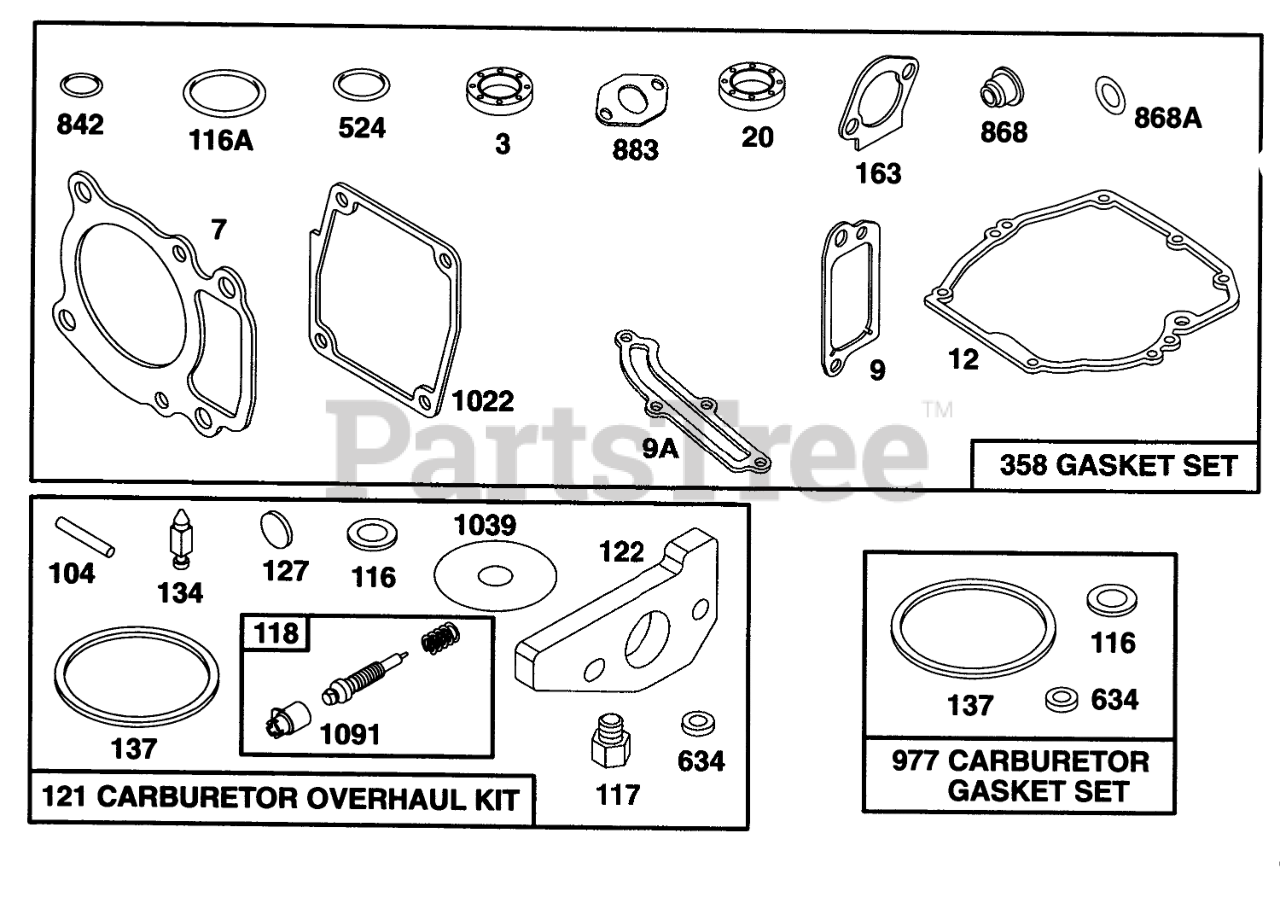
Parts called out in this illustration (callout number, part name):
3	SEAL - OIL
7	CYLINDER HEAD GASKET
9	BREATHER GASKET
9A	GASKET-BREATHER
12	ENGINE BASE GASKET
20	SEAL-OIL
104	FLOAT HINGE PIN
116	SEALING GASKET
116A	O RING SEAL
117	Jet-Main
118	VALVE/SPRING - NEEDLE
121	KIT-CARBURETOR OVERHAUL
122	ADAPTER ASSEMBLY
127	PLUG - WELCH
134	Valve-Inlet (Includes Seat)
137	FLOAT BOWL GASKET
163	AIR CLEANER GASKET
358	GASKET SET
524	O-RING
634	SEAL WASHER
842	O-RING
868	SealAssy-Valve
868A	Seal-Valve
883	EXHAUST GASKET
977	CARBURATOR GASKET SET
1022	ROCKER COVER GASKET
1039	FLOAT LIMITER
1091	CAP - LIMITER
